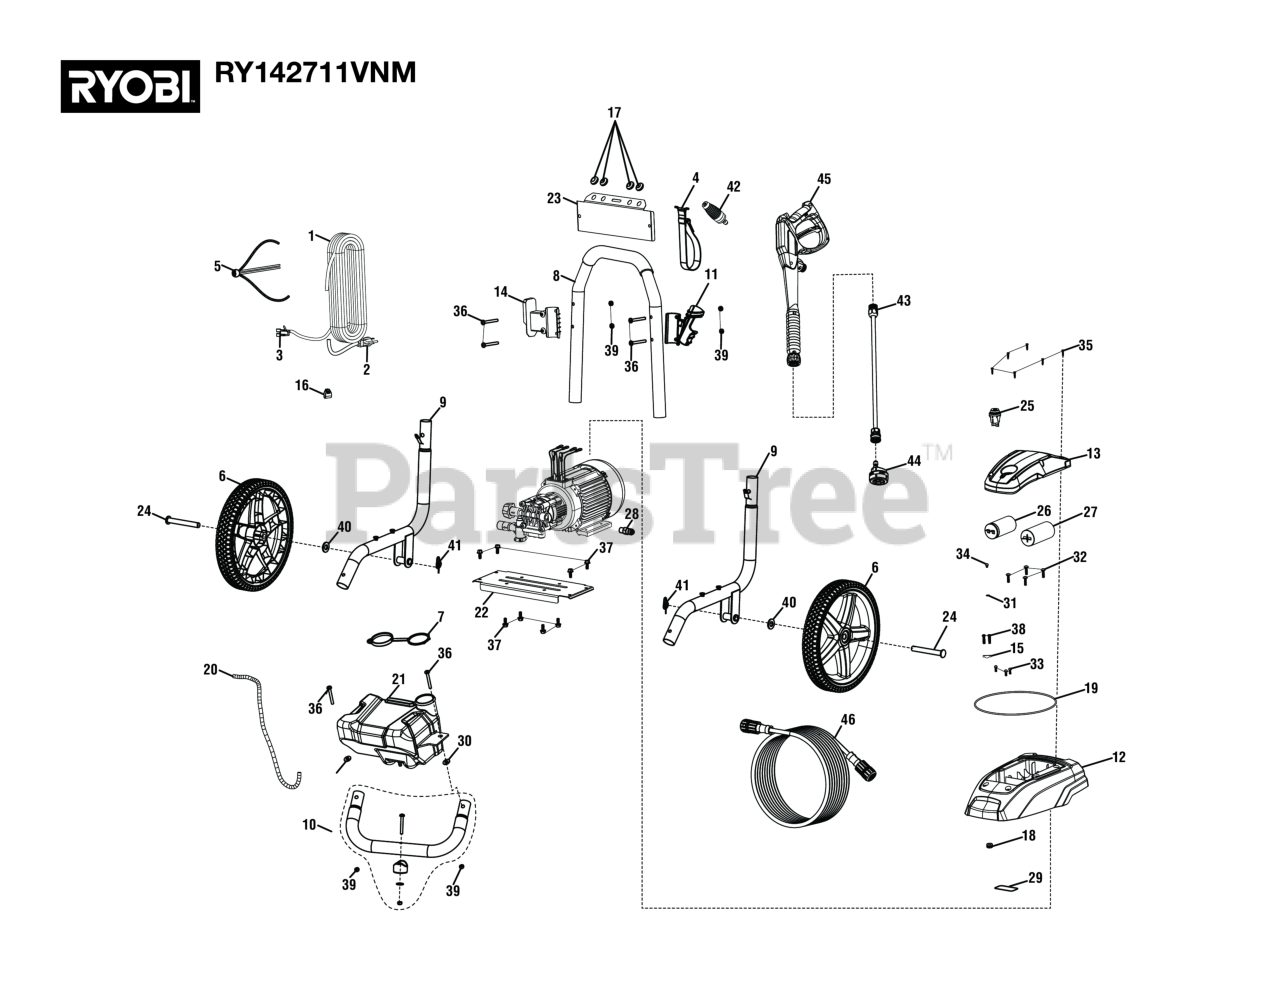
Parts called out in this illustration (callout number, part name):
1	Electrical Cord Assembly
2	Grounded Plug
3	Electrical Wire
4	Hose Holder Strap
5	Power Cord Strap
7	Detergent Tank Cap
8	Handle Assembly
9	Frame Assembly
10	Frame Assembly (Front)
11	Trigger Handle Holder
12	Motor Shroud
13	Upper Switch Cover
14	Cord Holder
15	Cord Clamp
16	Electric Cord Clip
17	Rubber Nozzle Grommet
18	Soap Tank Grommet
20	Chemical Siphon Tube
21	Detergent Tank
22	Motor Plate
23	Face Panel
25	On/Off Switch
26	Capacitor (CD60 250 VAC 300UF)
27	Capacitor (CBB60 SH PO 250 VAC 120UF)
28	Thermal Release Valve.
29	Wire Box Gasket (Lower)
30	Washer (1/4 in.)
31	Toothed Lock Washer (M4)
32	Bolt (M6 x 20 mm, Philips Pan Hd.)
33	Bolt (M4 x 12 mm, Pan Hd.)
34	Screw (M4 x 16 mm, Pan Hd.)
35	Screw (M4.2 x 15 mm, Phillips Hd. S.T.)
36	Screw (M6 x 1 x 48 mm, T30 Torx Pan Hd.)
37	Flange Bolt (M6 x 1 x 16 mm, Hex Hd.)
38	Screw (M3.5 x 20 mm, Button Hd.)
39	Lock Nut (M6 x 1)
40	Washer (1/2 in.)
41	Hitch Pin
42	Turbo Nozzle
43	Spray Wand Assembly
44	5-in-1 Nozzle Assembly
45	Trigger Handle Assembly
46	Hose (35 ft.)
